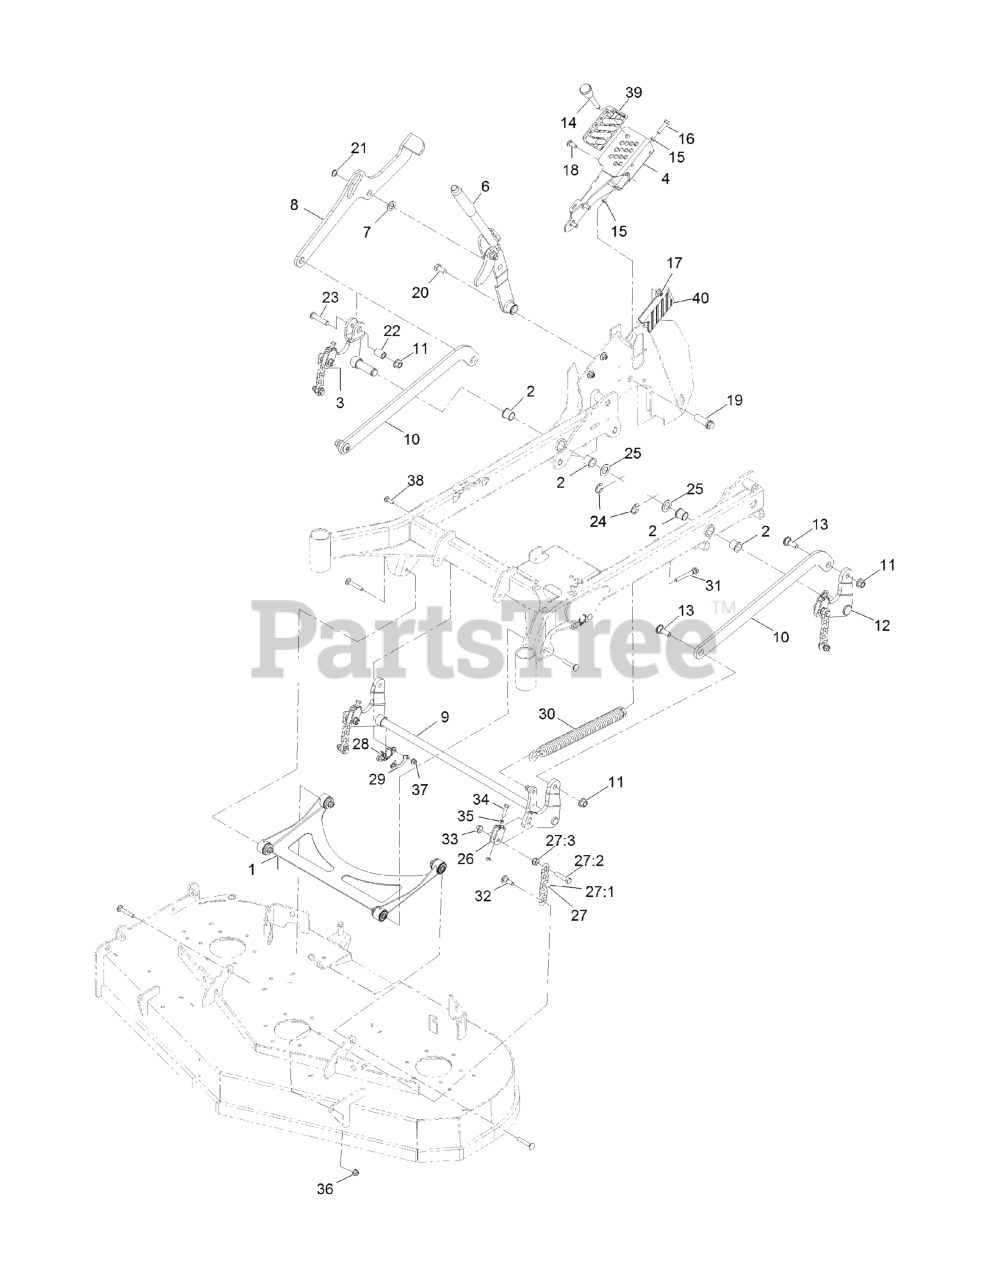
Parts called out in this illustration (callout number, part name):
2	BUSHING, IGUS
3	WELD, BELLCRANK, RT
7	WASHER-THRUST
9	WELD, HOC CROSS SHAFT
10	STRAP, HOC LIFT
11	Nut-Lock 1/2-13
12	WELD, BELLCRANK
13	BOLT, SHOULDER
14	PIN-HOC
15	NUT-JAM
16	BOLT-HH
17	Nut-Nyloc 3/8-16 Flg
18	SCREW-CARR
19	HUB-THREADED
20	SCREW-HH
21	RING-SNAP
22	SPACER, HOC
23	SCREW-HSBH
24	RING-RETAINING, EXT
25	Washer-Flat
26	YOKE-ADJUST, DECK
27	DECK LIFT CHAIN ASM
27:1	CHAIN-LIFT, DECK
27:2	SCREW-HH
28	BUSHING-FLANGE
29	GUSSET-LIFT, DECK
30	SPRING-EXTENSION
31	BOLT-SHOULDER
32	SCREW-SHOULDER, HHF
34	SCREW-HH
35	NUT-JAM
36	NUT-HF, NI
37	NUT-HF, NI
38	BOLT-CARR
39	DECAL-HEIGHT OF CUT
40	PAD, KNEE
